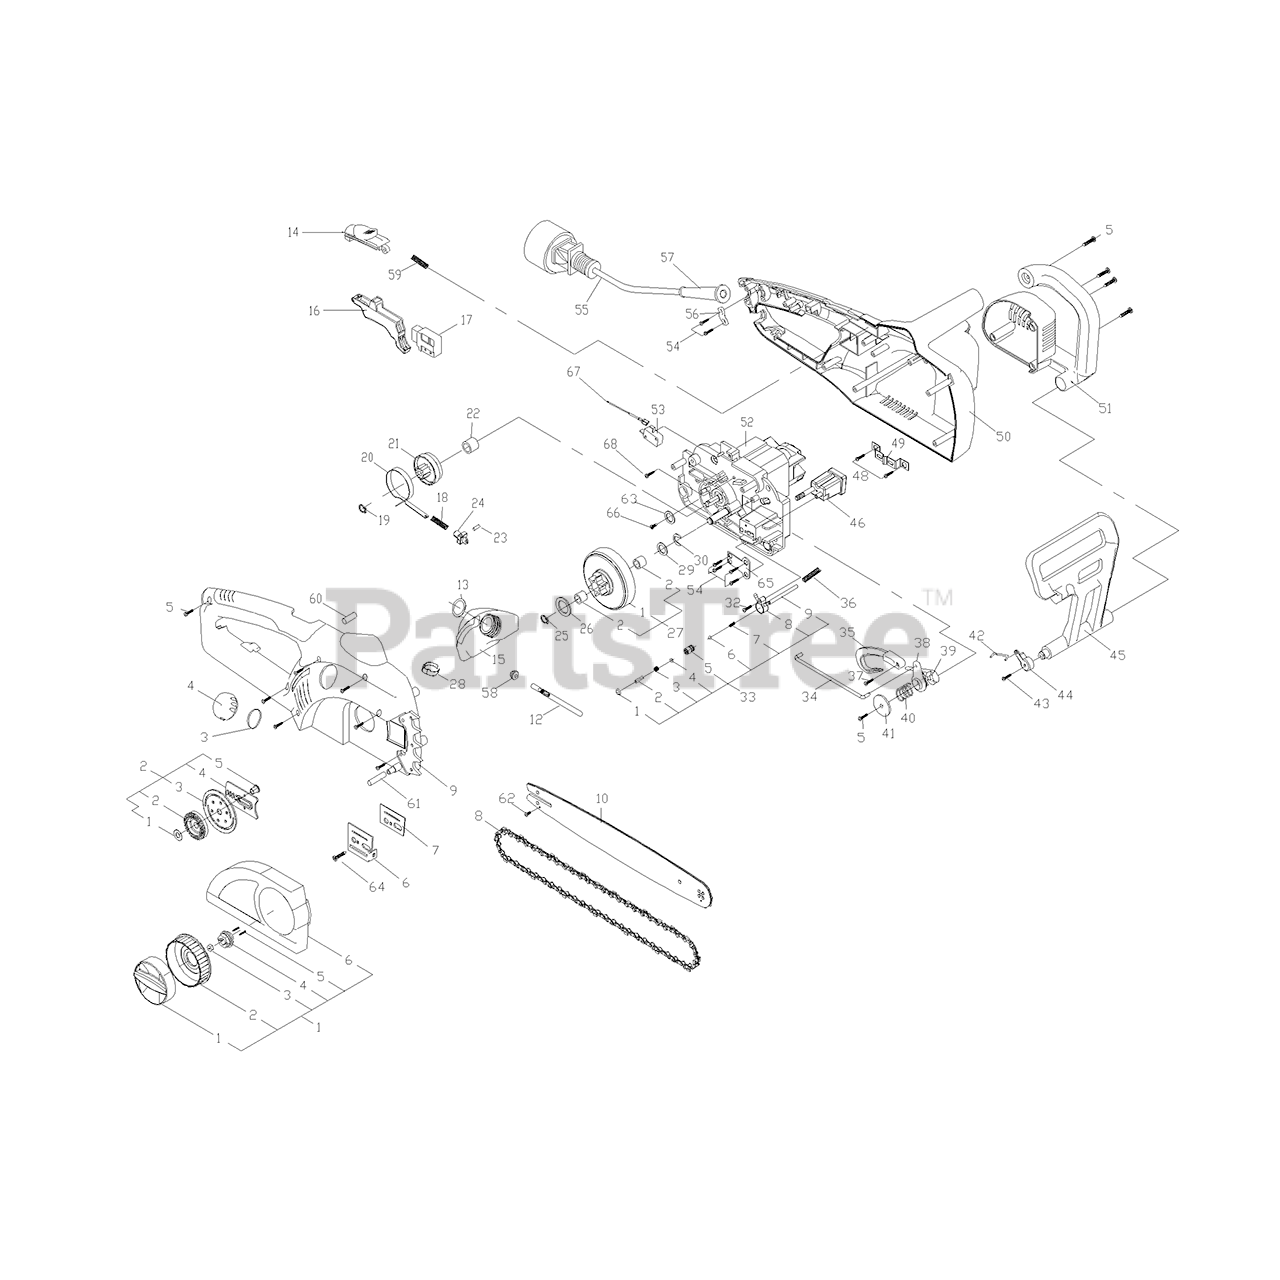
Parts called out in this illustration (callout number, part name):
1	HOUSING (R)
2	CHAIN COVER ASS'Y
3	WASHER
4	OIL COVER
5	SCREW
6	ADJUSTMENT PLATE
7	OIL WASHER
8	CHAIN
9	HOUSING (R)
10	BAR
12	OIL PIPE ASS'Y
13	WASHER
14	SWITCH BUTTON
15	OIL TENK
16	TRIGGER
17	SWITCH
18	SPRING
19	RING
20	SPRING, BRAKE
21	GEAR
22	ADJUSTMENT COVER
23	PIN
24	CONNECTION
25	C RING
26	WASHER
27	GEAR BEARING ASS'Y
28	COVER
29	WASHER
30	C RING
32	SCREW
33	OIL PUMP ASS'Y
34	PULL BAR
35	PULL PLATE
36	SPRING
37	SCREW
38	CLUTH
39	CLUTH
40	SPRING
41	WASHER
42	CONNECTING BAR
43	SCREW
44	CONNECTOR
45	FRONT-HAND GUARD
46	FIXED ACC'Y
48	SCREW
49	SPRING
50	HOUSING (L)
51	REAL COVER
52	MOTOR GEAR BOX ASS'Y
53	SWITCH
54	SCREW
55	POWER CORD
56	STRAIN RELIEF
57	CORD GUARD
58	RUBBER STOP
59	SPRING
60	PIN
61	PIN
62	SCREW
63	WASHER
64	SCREW
65	PLATE
66	SCREW
67	WIRE
68	SCREW
